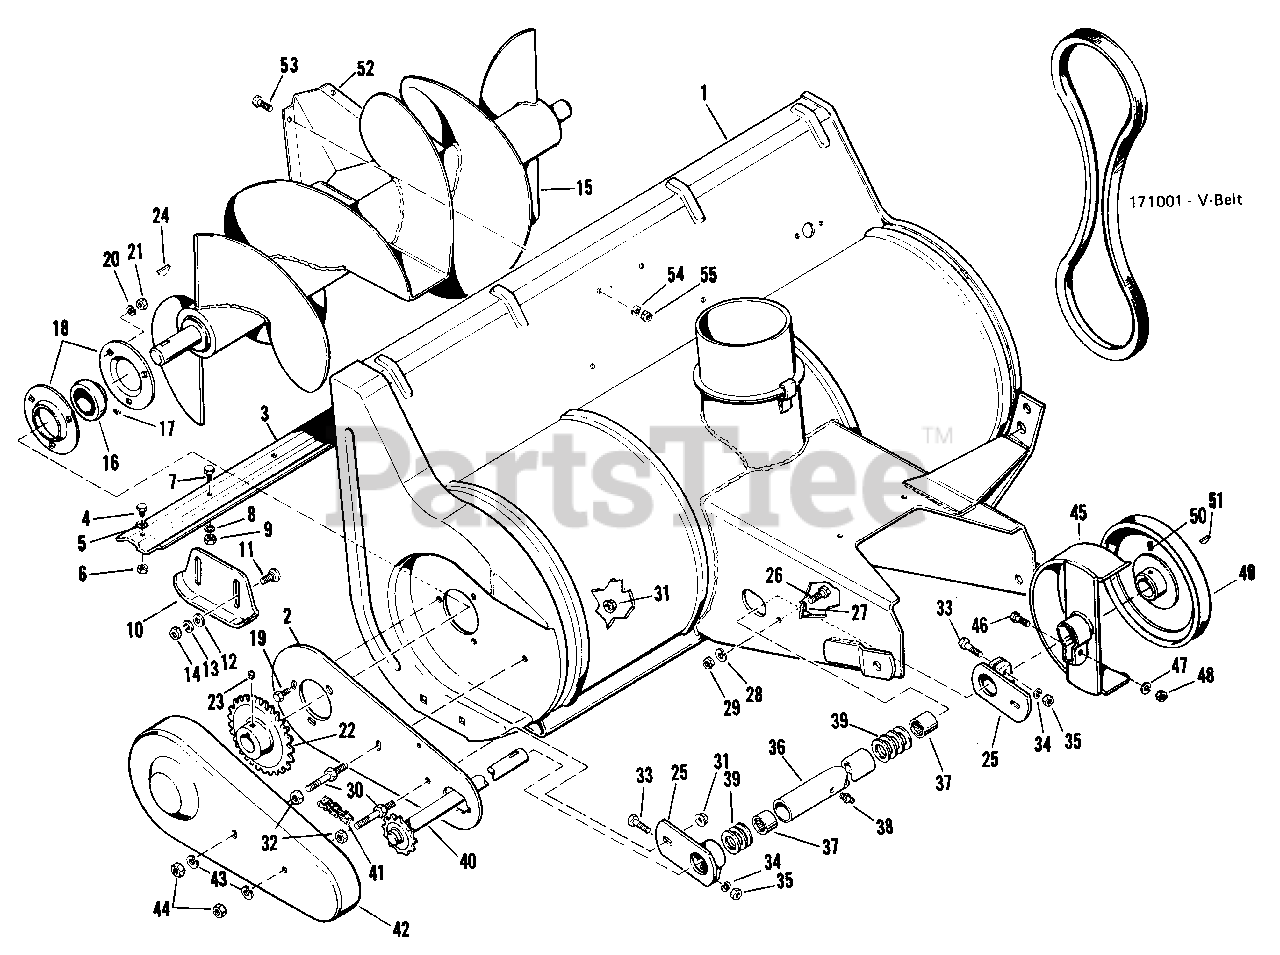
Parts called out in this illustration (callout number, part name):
1	Body Assembly
2	Side Plate
3	Body Scraper
4	Hex Capscrew, 5/16"-18 x 5/8"
5	Plain Washer, 1/4"
6	Hex Nut, Full Lock, 5/16"-18
7	Hex Capscrew, 1/4"-20 x 5/8"
8	Lock Washer, 1/4"
9	Hex Nut, Full, 1/4"-20
11	Carriage Bolt, 3/8"-16 x 3/4"
12	Plain Washer, 3/8"
13	Lock Washer, 3/8"
14	Hex Nut, Full, 3/8"-16
15	Rotor Assembly
16	Bearing Cartridge
17	Set Screw, 1/4"-28 x 1/4"
18	Bearing Flange
19	Hex Capscrew, 5/16"-18 x 3/4"
20	Lock Washer, 5/16"
21	Hex Nut, Full, 5/16"-18
22	Rotor Sprocket
23	Set Screw, 5/16"-18
25	Clamp Support Assembly
26	Hex Capscrew, 3/8"-16 x 1"
27	Plain Washer, 3/8"
28	Lock Washer, 3/8"
29	Hex Nut, Full, 3/8"-16
31	Nut, "Whiz Lock" 3/8-16
32	Hex Nut, Full, Lock, 3/8"-16
33	Hex Capscrew, 5/16"-18 x 1-1/2"
34	Lock Washer, 5/16"
35	Hex Nut, Full, 5/16"-18
36	Bearing Housing
37	Needle Bearing
38	Grease Fitting
40	Shaft Assembly
41	Chain W/Conn. Link
42	Chain Guard
43	Lock Washer
44	Hex Nut, Full, 3/8"-16
45	Belt Guard Assembly
46	Hex Capscrew, 5/16"-18 x 1-1/2"
47	Lock Washer, 5/16"
48	Hex Nut, Full, 5/16"-18
50	Set Screw, 5/16"-18 x 5/16"
53	Hex Capscrew, 5/16"-18 x 5/8"
54	Lock Washer, 5/16"
55	Hex Nut, Full, 5/16"-18
